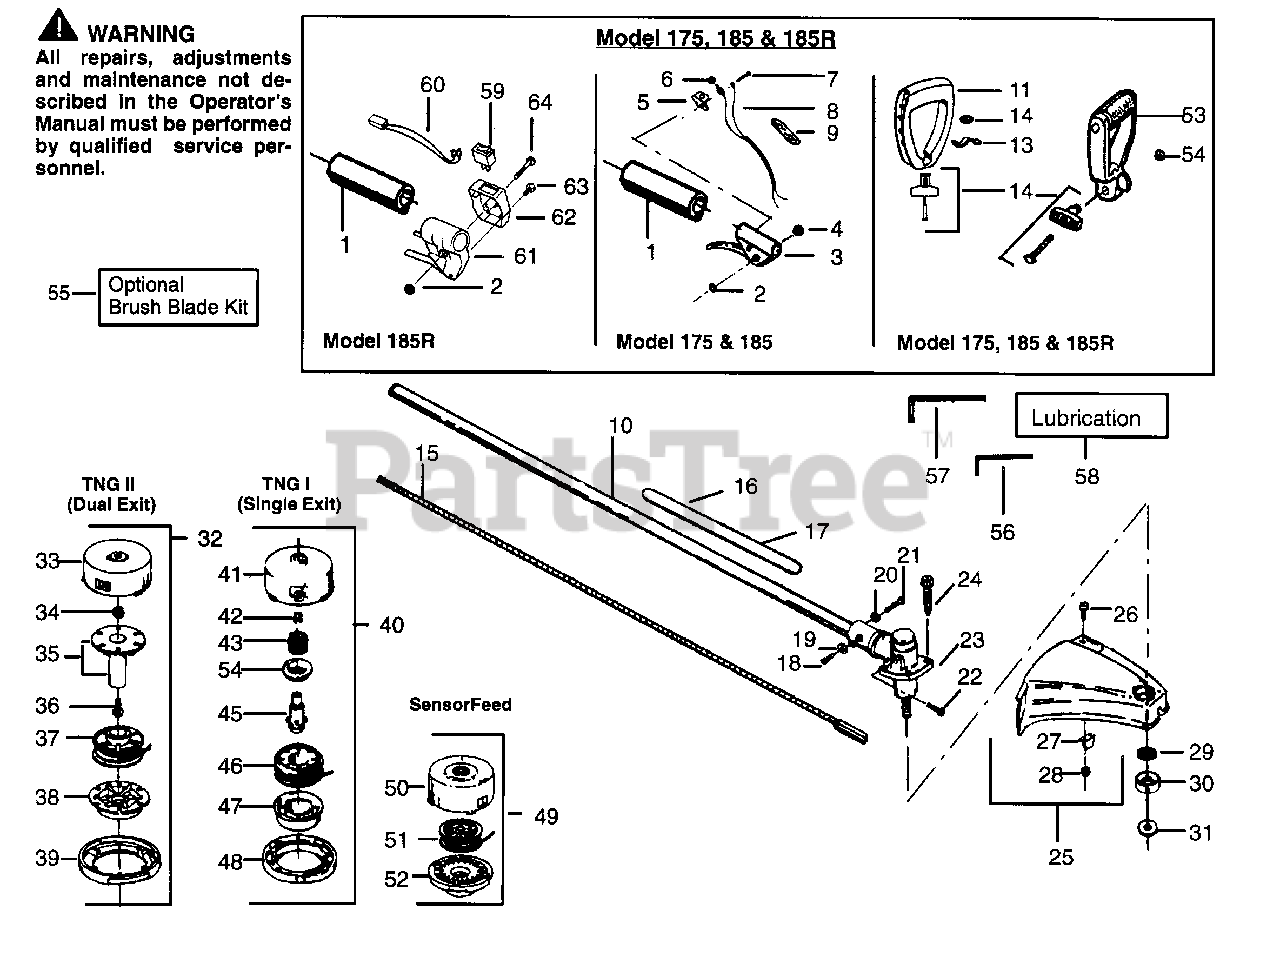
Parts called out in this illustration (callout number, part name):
1	Drive Shaft Grip
3	Throttle Lever Ass'y. w/Lock (Inc. 2 & 4)
5	Switch Bracket
6	Nut
8	Wire Harness Ass'y.
9	Terminal Lock
10	Drive Shaft
14	"T" Handle Ass'y.
15	Drive Shaft Hsg.
16	Decal - Upper
17	Decal - Lower
19	Lockwasher
20	Lockwasher
23	Gear Box Ass'y.
25	Shield Kit Ass'y. (Inc. 26-28)
27	Line Limiter
28	Locknut
30	Dust Cup
31	Grass Washer
32	Dual Exit Cutting Head (Inc. 33-39)
33	Hub Ass'y.
35	Locking Plate Kit
37	Spool w/Line
38	Release Button
40	Single Exit Cutting Head (Inc. 41-48)
41	Hub Ass'y
42	Line Saver
44	Spring Cap
45	Drive Gear
46	Spool w/Line
47	Release Buttong
49	Single Exit Cutting Head (Inc. 50-52)
50	Hub Ass'y
51	Spool w/ Line
55	Brush Blade Kit
56	Hex Wrench (5/32)
57	Hex Wrench (3/16)
58	Shaft Lubrication
59	Rocker Switch
60	Leadwire
61	Ass'y Throttle Hsg.
62	Switch Cover
63	Screw (Short)
64	Screw (Long)
